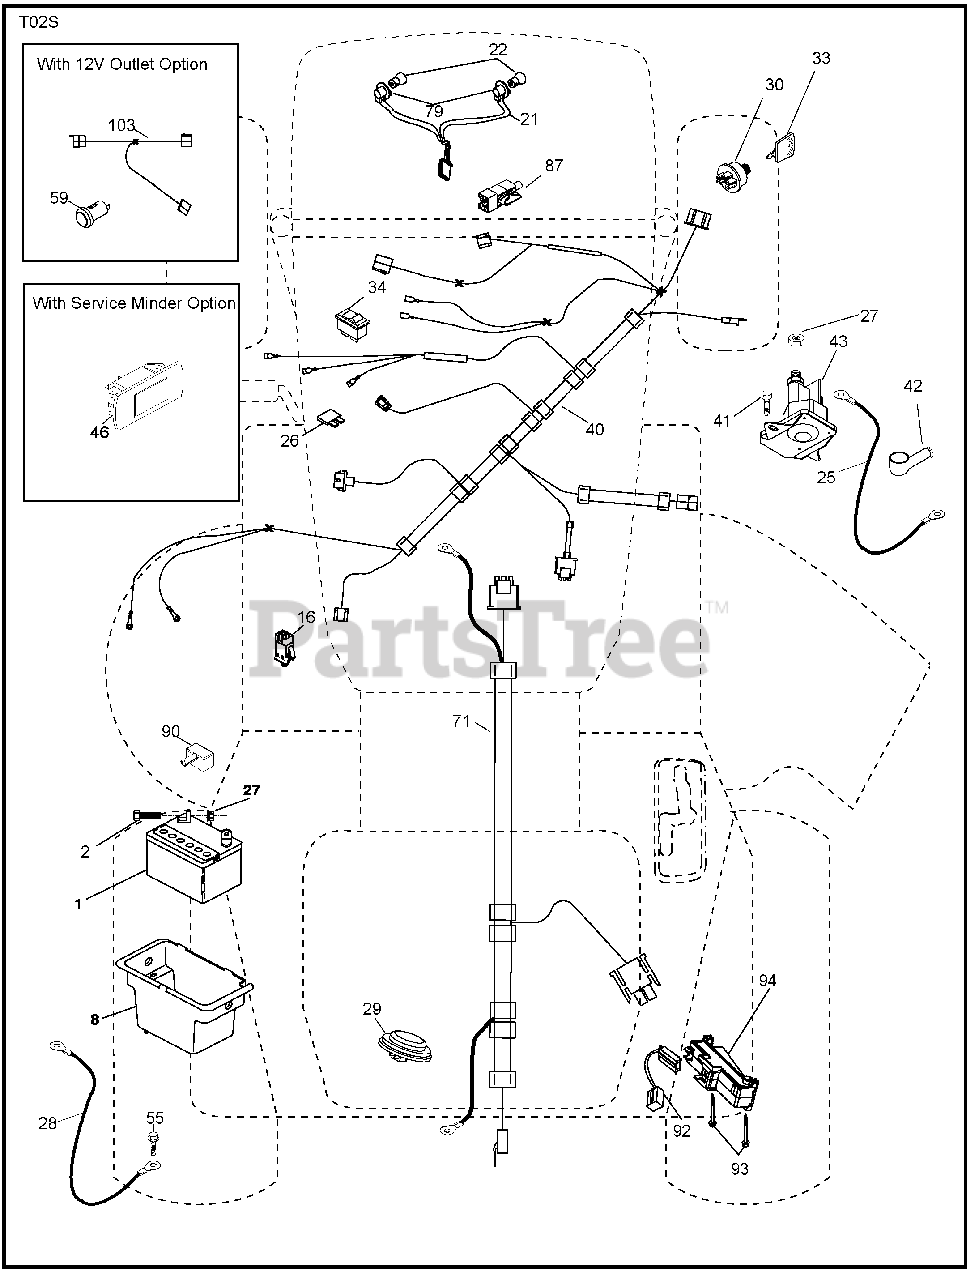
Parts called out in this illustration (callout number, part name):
1	Battery
2	Bolt Hex Head 1/4-20 x 3/4
8	Box Battery
16	Switch Interlock Push-In
21	Harness Socket Light w/4152J
22	Bulb Light
25	Cable Starter
26	Fuse
27	Nut Keps Hex 1/4-20 unc
28	Cable, Ground
29	Switch, Seat
30	Switch, Ignition
33	Key/Chain
34	Switch Light/Reset
40	Harness Ignition Dash
41	Screw Thd Cut 1/4-20 x 1/2
42	Cover, Terminal
43	Solenoid
46	Gauge SRVCMNDR HRMTR
55	Screw Thdrol 5/16-18 x 3/4 TYTT
71	Harness Ignition
79	Socket Asm Bulb Twistlock
87	Switch Interlock Clutch Cable
90	Cover Terminal Battery
92	Harness Pigtail Console ROS
93	Screw Plastite 10-14 x 2.0
94	Module Reverse ROS
